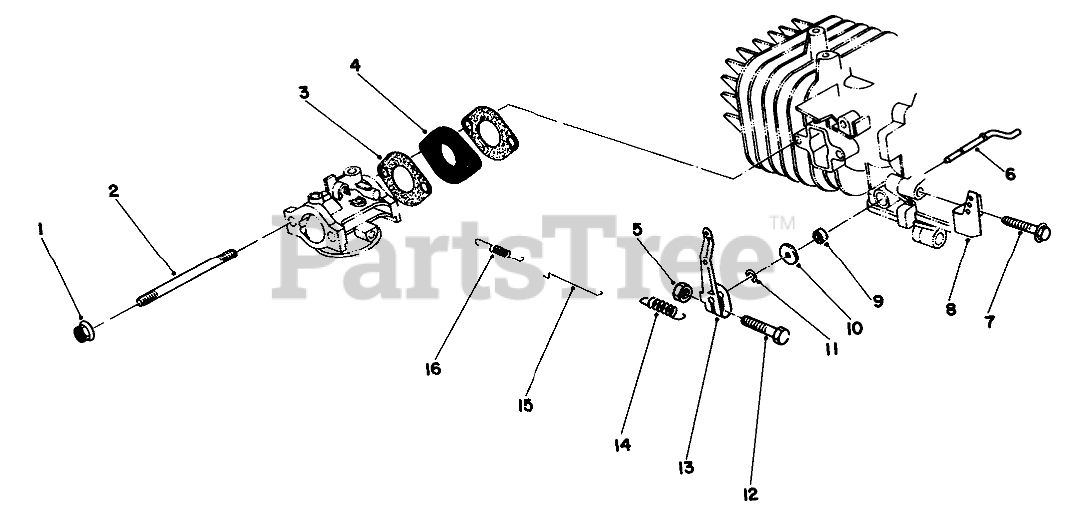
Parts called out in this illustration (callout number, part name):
1	M6 X 1 LOCKNUT
2	Stud-Bolt-Carburetor
3	GASKET-CARB
4	CARB. INSULATOR
6	Shaft-Govemor
8	Bracket-Governor Spring
9	SEAL-OIL
10	WASHER
11	E-RING
13	Lever-Throttle Control
14	SPRING
15	ROD-CARBURETOR
16	Spring-Governor
